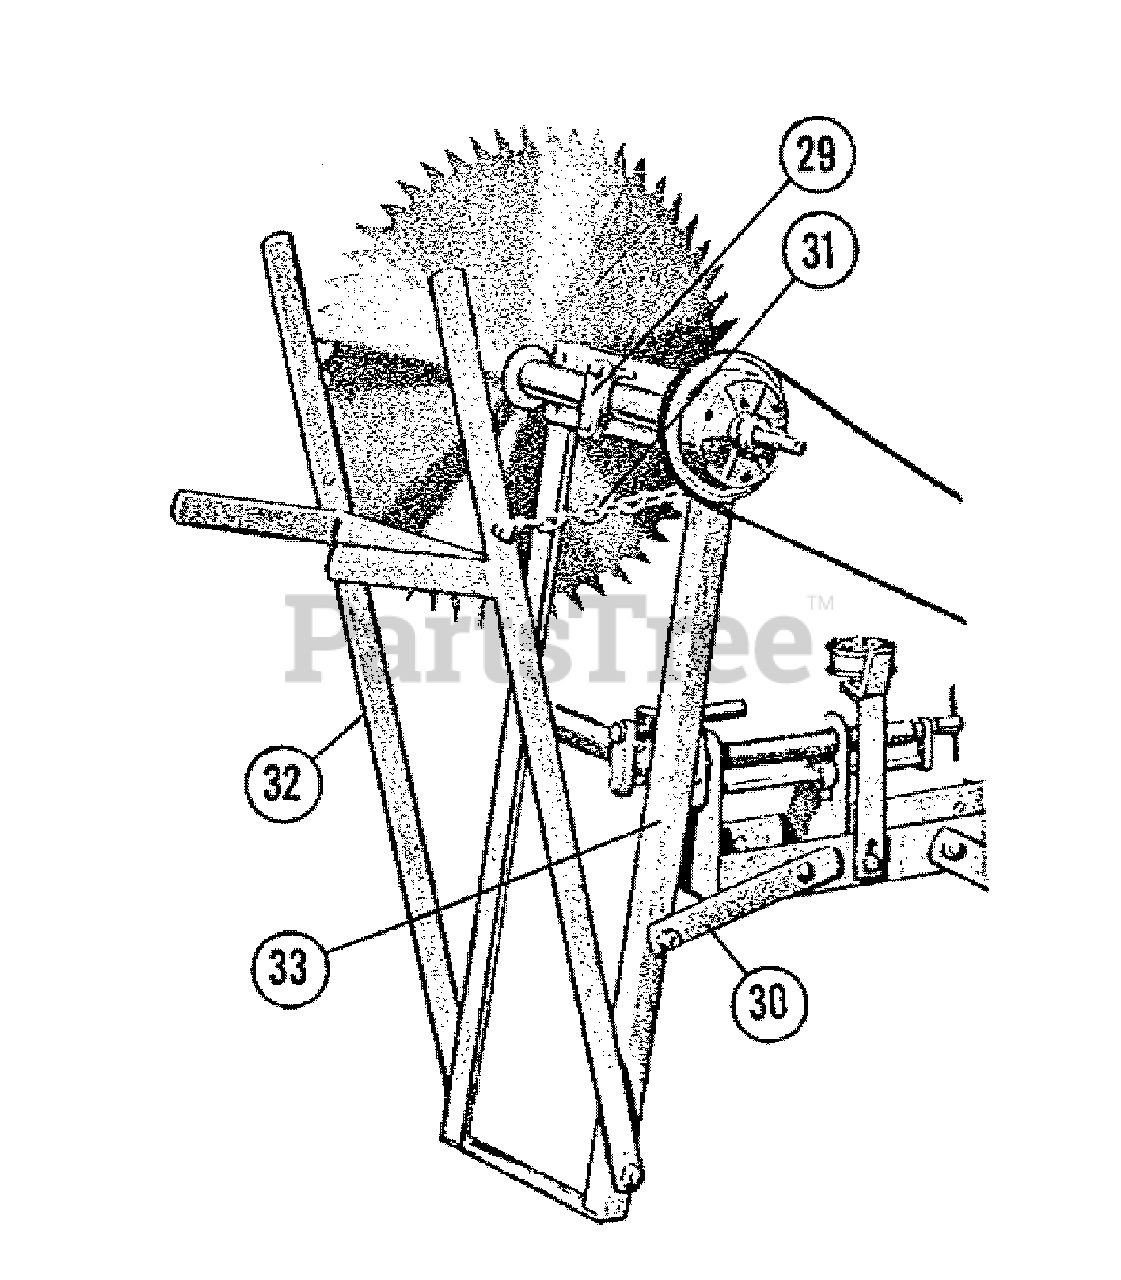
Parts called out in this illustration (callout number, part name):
2	CRADLE HOLDER
3	CRADLE CHAIN
4	CRADLE ASSEMBLY
5	CRADLE FRAM ASSEMBLY
